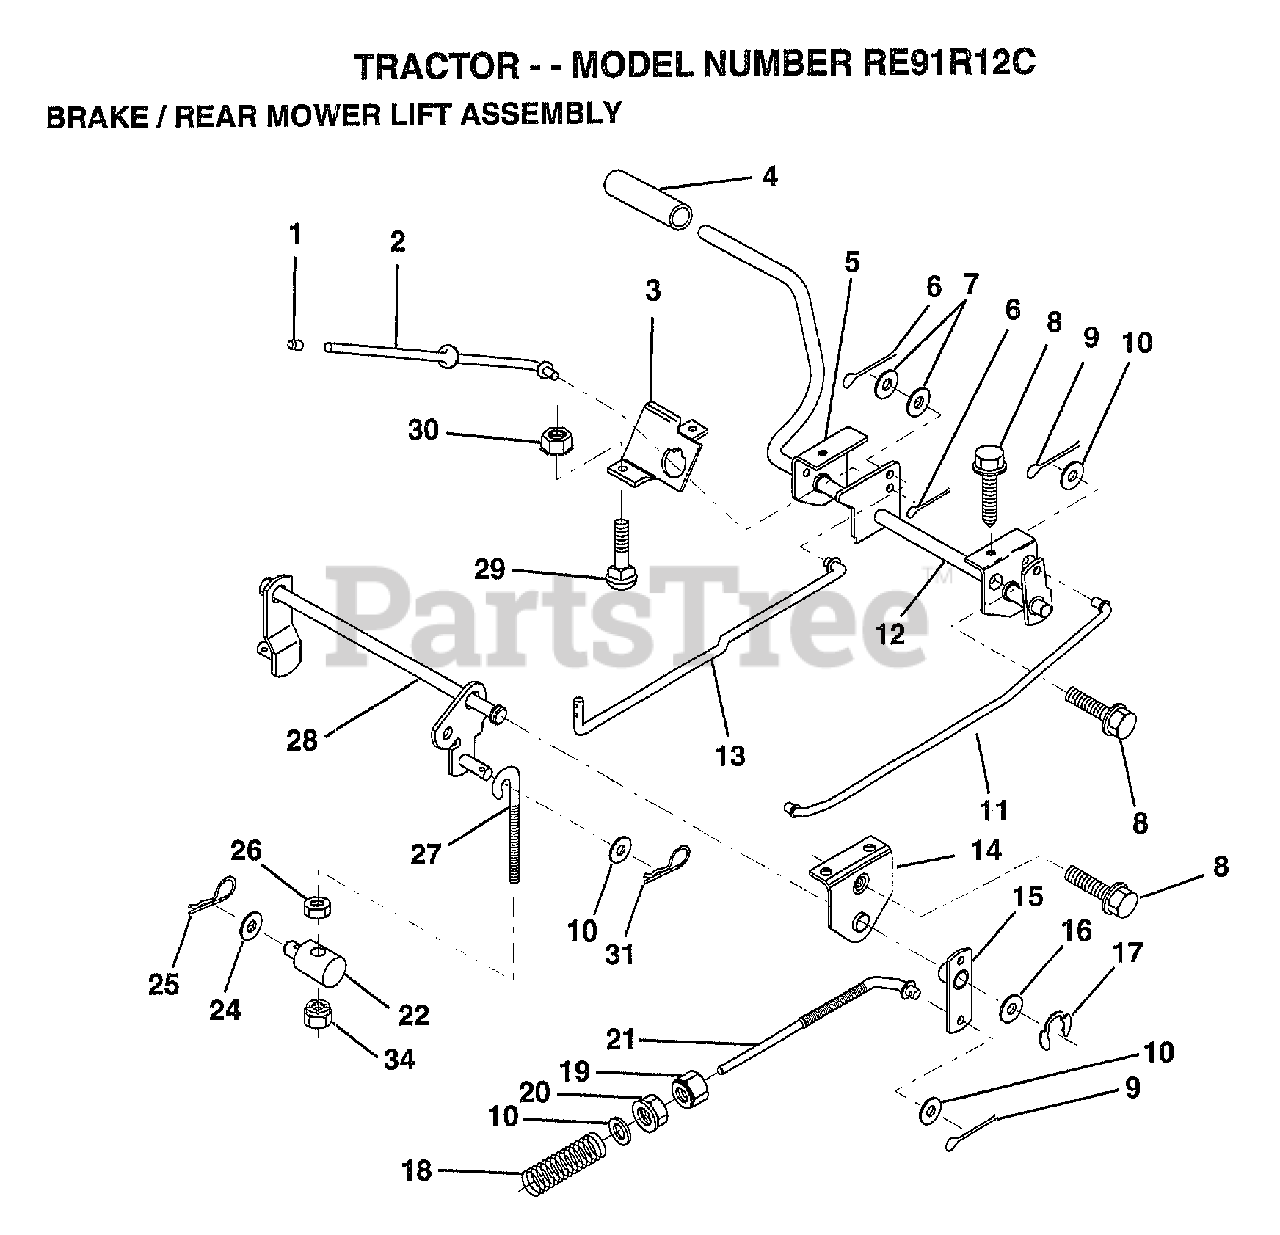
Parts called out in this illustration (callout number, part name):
1	PLUNGER CAP T
2	"ROD,PARK BRAKE"
3	"BRKT,PARK BRAKE"
4	FOOT PEDAL COVER
5	"BRKT,CLU PEDAL LH"
7	WASHER
8	SCREW LT
9	COTTER PIN
10	WASHER
11	"ROD,FRT BRAKE"
12	PEDAL ASM CL/BK36
13	"ROD,CLUTCH"
14	"BRKT,LIFT SHAFT"
15	PVT BRAKE ARM ASM
16	WASHER T
17	KLIP RING
18	SPRING ROD BRAKE
19	NUT
20	NUT
22	TRUNNION.LIFT.
24	WASHER
25	SPRING.RETAINER
26	LOCKNUT
27	"LINK, MOWER REAR"
28	LIFT ASM MOW REAR
31	RETAINER.SPRING
